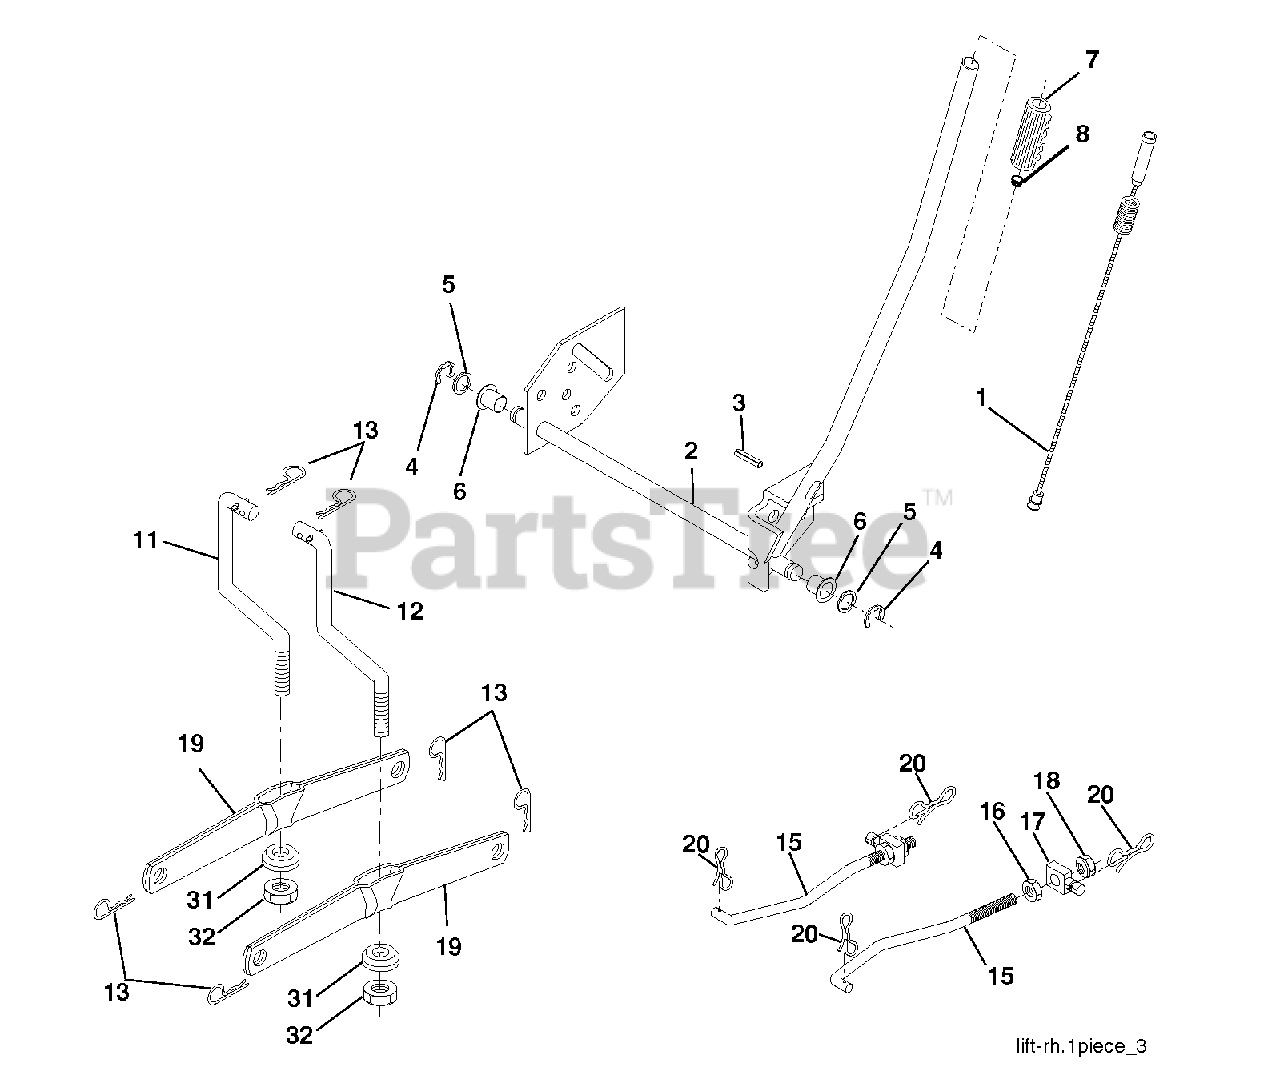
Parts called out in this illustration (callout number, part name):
1	PLUNGER.ASM.LIFT.LVR.B*SUBS/2*
2	SHAFT.ASM.LIFT.YT
3	Groove Pin, 5/16
4	RETAINING RING LT
6	BEARING.NYLON
7	GRIP
8	PLUNGER BUT KIT
11	LINK
12	LINK
13	RETAINER-SPRNG RB
15	LINK.SUSPENSION.FRONT
16	NUT
18	NUT
19	ARM.REAR.SUSPENSION
20	PIN.COTTER.7/16.BOW TI
31	BEARING.PIVOT.LIFT
32	NUT CROWNLOCK 3/8-24
